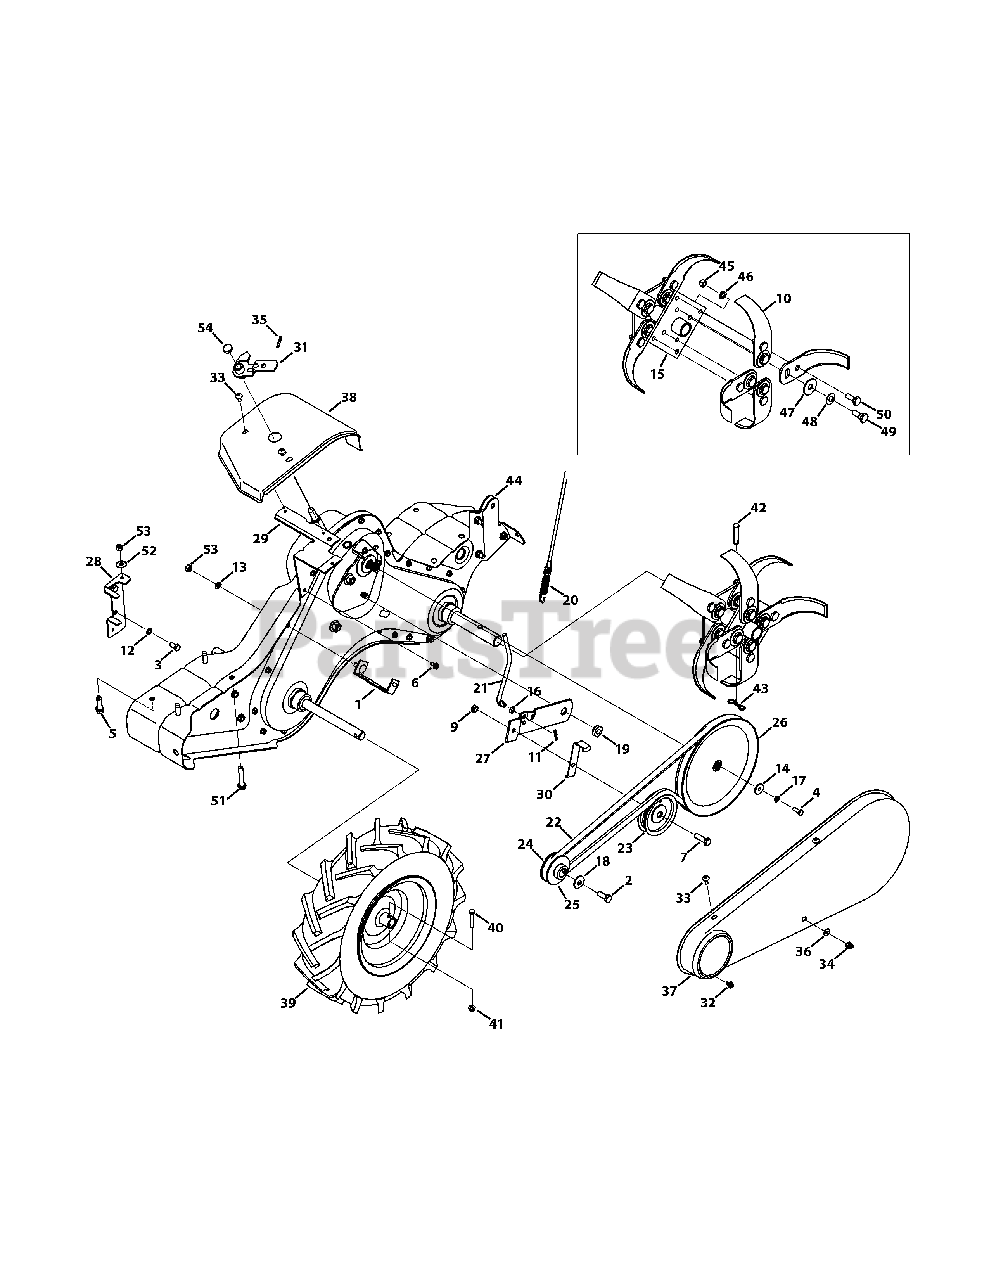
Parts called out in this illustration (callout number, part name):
1	Belt Cover Bracket Assembly
2	Hex Head Screw, 3/8-24 x 1.00
3	Hex Head Screw, 5/16-24 x .625
4	Hex Head Screw, 1/4-28 x .75
5	Screw, 3/8-16 x 1.250
6	Screw, 1/4-20 x 0.500
7	Hex Head Screw, 3/8-16 x 1.25
8	Hex Head Screw, 5/16-18 x 1.50
9	Jamlock Nut, 3/8-16
10	Articulating Tine
11	Cotter Pin, .072 DIA. x 1.13 LG
12	Washer, Lock, 5/16
13	Washer, Lock, 5/16
14	Washer, Flat, .265 x .938 x .120
15	Tine Adaptor Assembly
15	Tine Assembly
16	Washer, Spring, .317 x .625 x .020
17	Washer, Lock, 1/4
18	Washer, Bell, .396 x 1.140 x .095
19	Shoulder Nut, 7/16-20
20	Clutch Cable
21	Idler Pulley Rod
22	Belt, 4L x 58.16 LG
23	Flat Idler Pulley w/ Flanges, 3.75 O.D.
24	Engine Pulley, Inner Half
25	Engine Pulley, Outer Half
26	Input Pulley, 4L x 8.594
27	Idler Pulley Bracket
28	Belt Keeper Bracket
29	Shaft Cover Bracket
30	Idler Belt Keeper
31	Shaft Crank Assembly
32	Screw, 1/4-20:0.375
33	Screw, 1/4-14:0.625
34	Lock Nut ,Cap, 1/4-28
35	Spiral Pin, 3/16 x 1.00
36	Washer, Flat, .271 x .630 x .065
37	Belt Cover
38	Shaft Cover
39	Wheel, 16 x 4.6 x 8
40	Hex Head Screw, 1/4-20 x 1.50
41	Flangelock Nut, 1/4-20
42	Clevis Pin, .375 x 1.75
43	Cotter Pin, Bow Tie
44	Complete Gear Case Assembly
45	Hexlock Nut, 3/8-24
46	Washer, Lock, 3/8
47	Washer, Flat, .51 x 1.5 x 0.07
48	Washer, Bell, .525 x 1.00 x .050
49	Screw, Shoulder, 3/8-24 x 1/2 x .325
50	Screw, Shoulder, 3/8-24 x 1/2 x .180
51	Hex Head Screw, 5/16-18 x 1.50
52	Washer, Bell, .340 x .872 x .060
53	Hex Nut, 5/16-18
